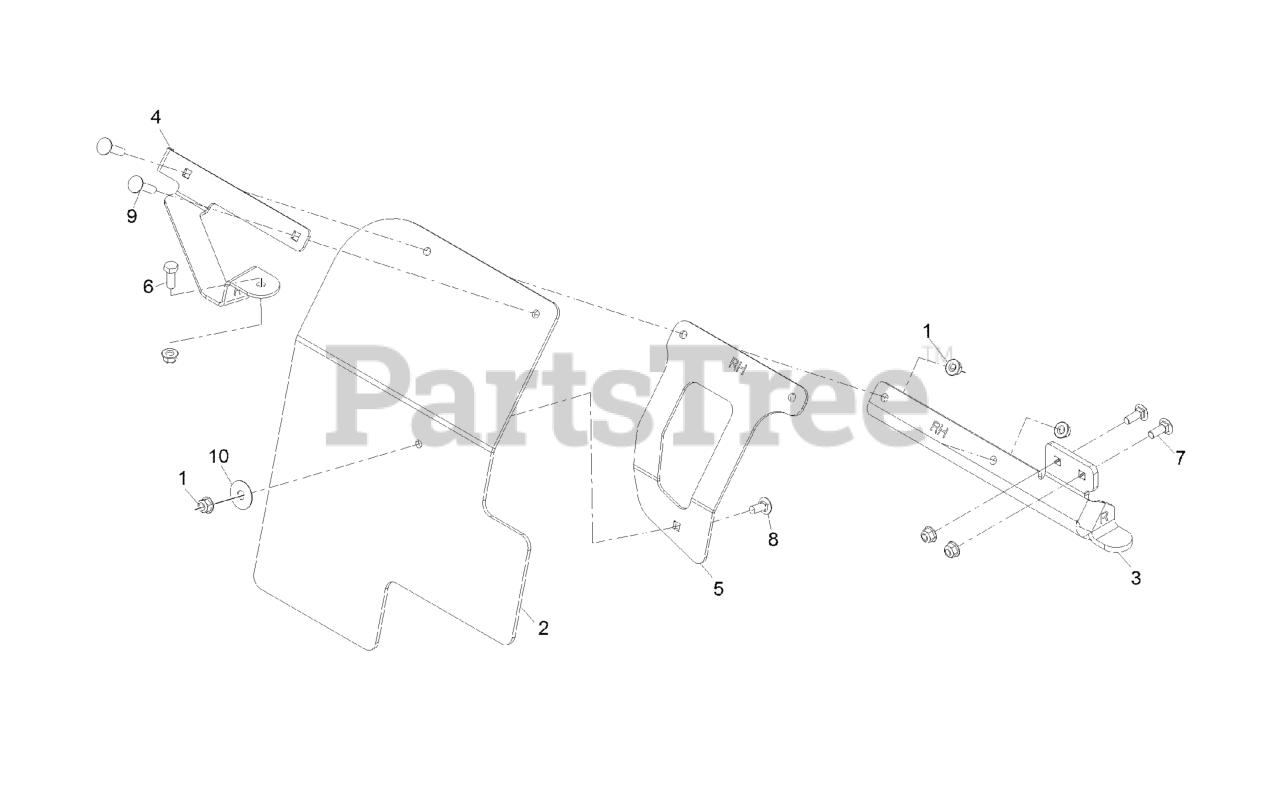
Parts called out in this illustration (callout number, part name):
1	NUT-HF, NI
2	RH MUD FLAP
3	BRACKET, RH MUD FLAP
4	FORWARD SUPPORT, RH MUD FLAP
5	SUPPORT, RH MUD FLAP
6	SCREW-HH
7	SCREW-CARR
8	SCREW-CARR
9	Bolt-Carriage 5/16-18 X 1 1/4
10	WASHER-PLAIN
